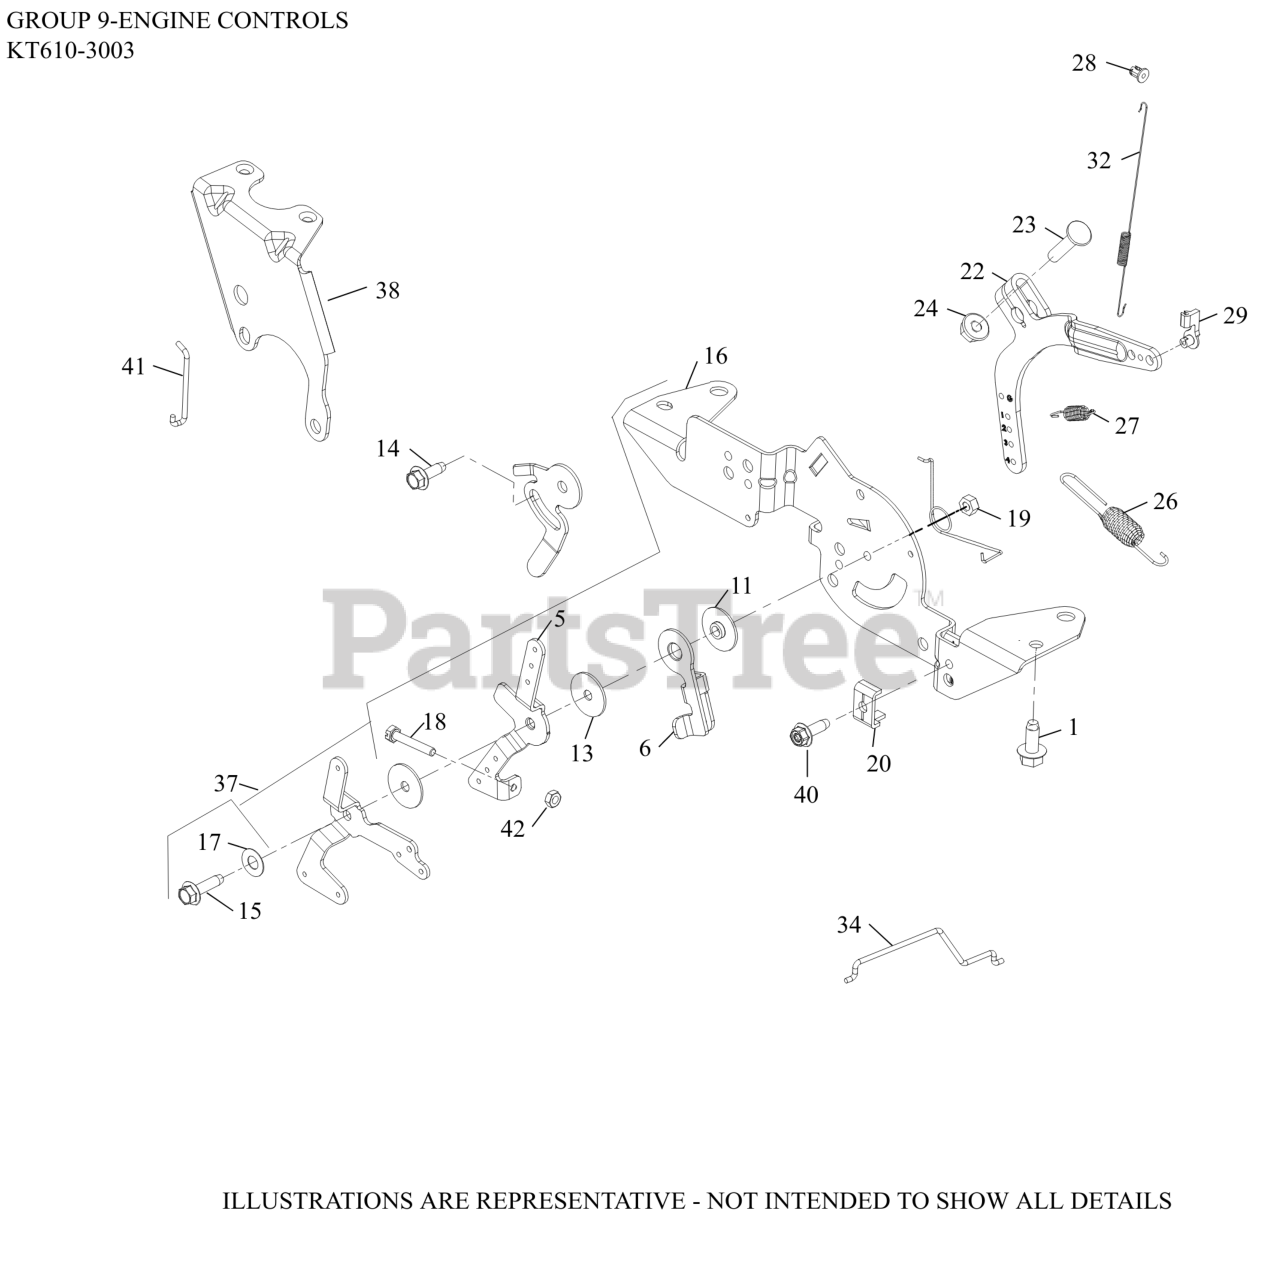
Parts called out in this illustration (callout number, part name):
1	SCREW, THREAD FORMING
5	LEVER, THROTTLE CONTROL
6	LEVER, THROTTLE ACTUATOR
11	SPACER, CONTROL ASSEMBLY
13	WASHER, FLAT 5 MM
14	SCREW, THREAD FORMING
15	SCREW, THD FRM-USE 25 086 473-S
16	BRACKET, SPEED CONTROL
17	WASHER, SPRING 1/4"
18	SCREW, SLT HD CAP M4X0.7X25
19	NUT, LOCK M5X.8
20	CLAMP, CABLE-(#2523753S)
22	LEVER, GOVERNOR - (#2409069S)
23	BOLT, RD HD SQ NECK M6X1.0X25
24	NUT, FLG M6X1.0
26	SPRING, GOVERNOR (ORANGE)
27	SPRING, GOVERNED IDLE
28	BUSHING, LINKAGE RETAINING
29	BUSHING, THROTTLE LINKAGE
32	SPRING, LINKAGE
34	LINKAGE, THROTTLE
37	SPEED CONTROL, ASSEMBLY
38	BRACKET, AUTO-CHOKE
40	SCREW, THREAD FORMING
41	LINKAGE CHOKE
42	NUT, M4X0.7
